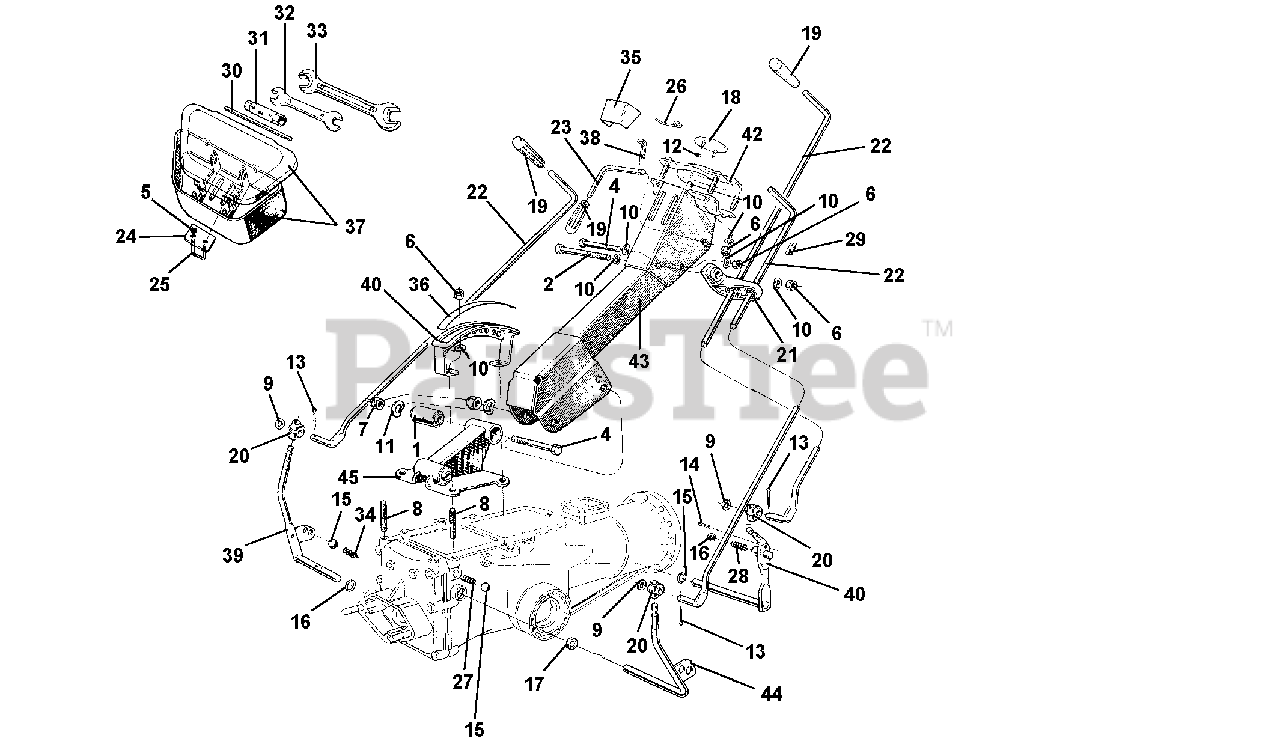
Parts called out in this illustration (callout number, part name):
1	SILENTBLOCK
2	SCREW TE M8 X 100
3	SCREW TE M10 X 70
4	SCREW M8 X 60
5	NUT, SELF LOCKING M6
6	NUT, SELF LOCKING M8
7	NUT, SELF LOCKING M10
8	STUD M8 X 38 X 14 X 20
9	WASHER P10.5 X 18
10	WASHER, LOCK 8.4
11	WASHER, LOCK 10.5
12	WASHER, LOCK FOR PINS
14	LOCKING PIN SPIRAL
15	BALL 15/32 RIV RB-11.906
16	O-RING 115 11.91 X 2.62
17	SEAL, OIL 12 X 19 X 5 STANDARD
20	JOINT, D 10
21	ROD SUPPORT
22	ROD, CONTROL, POWER TILLER
23	LEVER FOR SECTOR
26	SHEATH HOOK
29	PLATE SLOW/FAST SPEEDS
30	PARALLEL PIN D 7 X 130
31	TUBE KEY 10 - 13
32	OPEN KEY 13 - 17
33	OPEN KEY 19 - 22
34	P.T.O. SPRING
35	ADHESIVE LABEL 604
36	PLATE, SPEEDS
37	NEUTRAL TOOL BOX
39	P.T.O. LEVER
40	MOTOR MOWER GEARBOX LEVER
43	MOTOR MOWER STEERING COLUMN
44	SHIFT LEVER
45	SUPPORT COMPL. SILENTBLOCK
